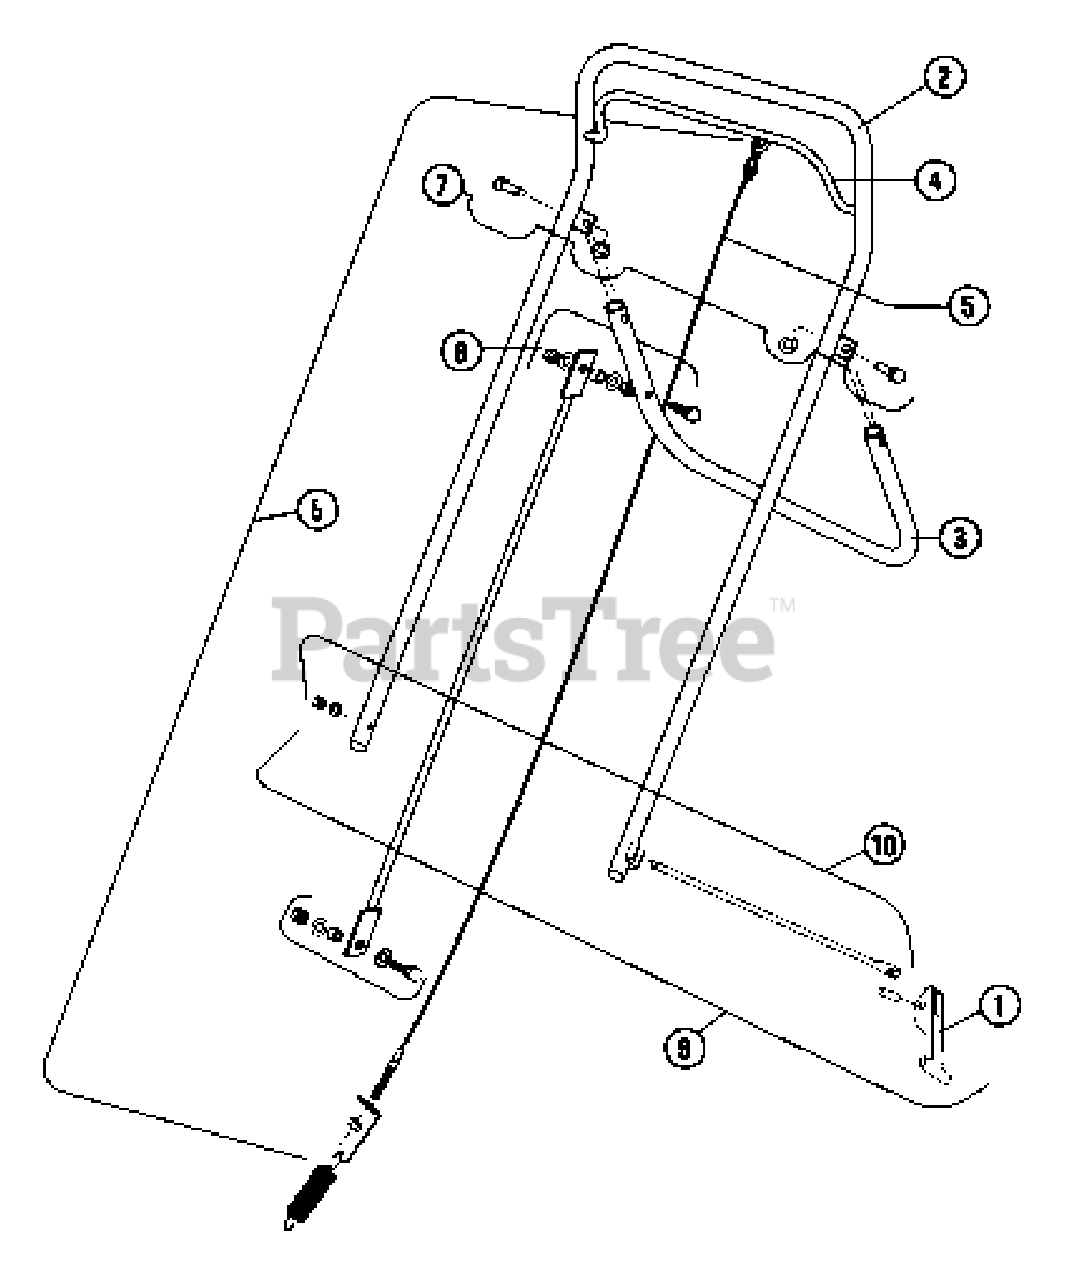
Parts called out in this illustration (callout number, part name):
1	Cam, locking
2	Handle
3	Handle, control, rear wheel
5	Clutch cable
6	Clutch cable kit
7	Pin kit, rear wheel control handle
8	Control rod kit, rear wheel
9	Cam rod kit, with cam
10	Cam rod kit, without cam
